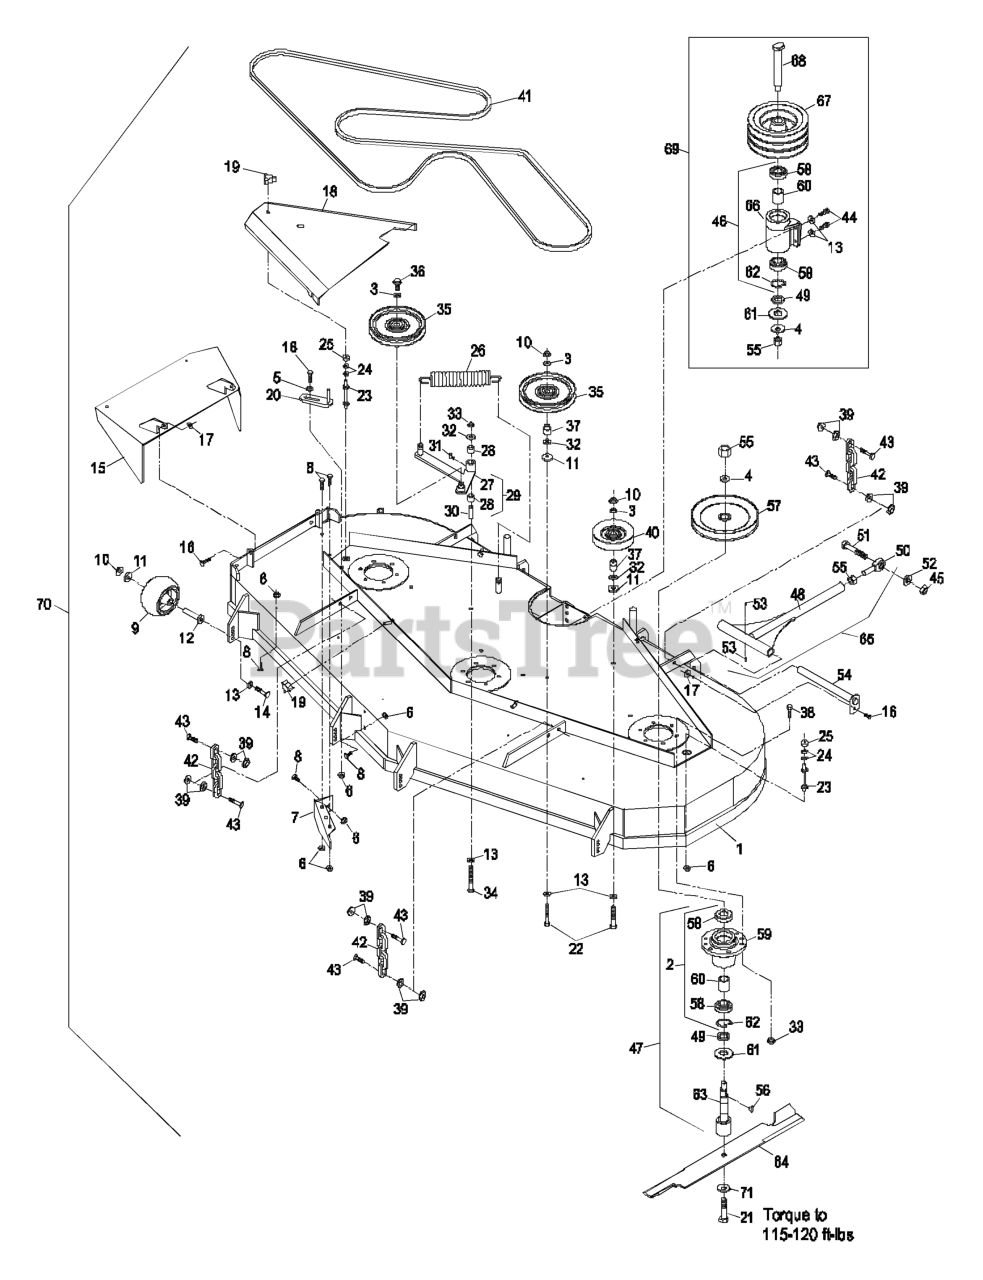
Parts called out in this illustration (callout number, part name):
3	WASHER-FLAT
4	WASHER-SPRING
5	WASHER-SPRING
7	WLD,BAFFLE DISCHARGE
8	SCREW-HH
9	ROLLER-SCALP, ANTI
10	NUT-HHF, WHIZ
12	BUSHING-ROLLER
13	WASHER-BELLEVILLE
14	SCREW-HH
15	WLD,CHUTE 72
16	SCREW-HH
17	NUT-LOCK, NI
18	SHIELD,BELT RH
19	KNOB-3 PRONG
20	GUIDE-BELT
21	SCREW-CAP
22	SCREW-HH
23	STUD-SHIELD, BELT (SHORT)
24	WASHER-FLAT
28	SLEEVE-BEARING
30	BUSHING
31	FITTING-GREASE, 90 DEG
32	WASHER-FLAT
33	NUT-LOCK, NI
34	SCREW-HH
36	SCREW-HHF
37	BUSHING-IDLER
38	SCREW-HH
40	PULLEY-IDLER
41	BELT-V
42	CHAIN-LIFT, DECK
43	SCREW-CAP, HH
44	SCREW-HH
45	NUT-HEX
47	SPINDLE HSG ASSYCOMP72
49	SPACER-PULLEY/BEARING
50	BALLJOINT-SPHERICAL
51	SCREW-HH
52	WASHER-LOCK
53	FITTING-GREASE
54	PIN-STRUT
55	NUT-HEX
56	KEY-WOODRUFF
57	SHEAVE,BLADE DRIVE7.5EOD
58	BEARING
60	SPACER-BEARING
61	GUARD-BEARING, BOTTOM
62	RING-SNAP
65	STRUT WLDMT S/A
68	JACKSHAFT,LAZER XP
69	ASM,JACKSHAFT
70	Complete Deck Assy
71	WASHER-BLADE BOLT, HEAVY
